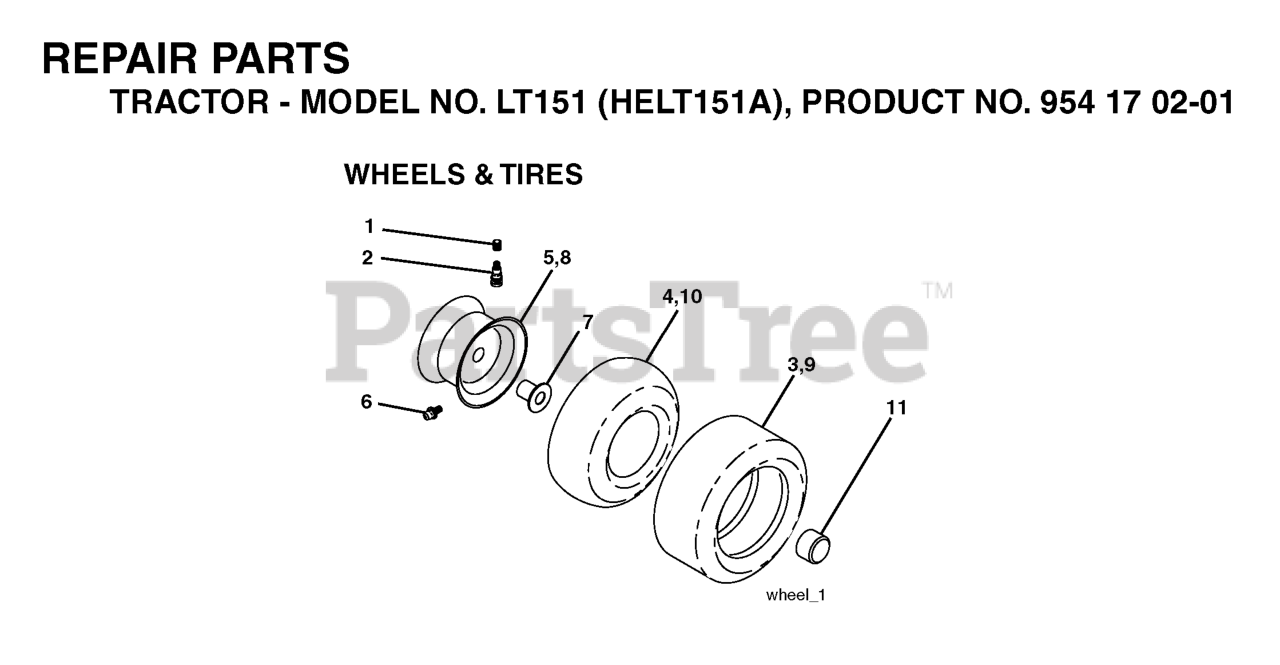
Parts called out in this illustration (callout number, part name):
2	VALVE STEM LT
3	TIRE HEAVY DUTY
4	TUBE.5.3/4.5/6
5	RIM ASM 6" FRONT SILVER
6	FITTING LT
7	BEARING T
8	RIM ASM 8" REAR SILVER
9	TIRE HEAVY DUTY
10	TUBE
11	CAP, AXLE BLK
